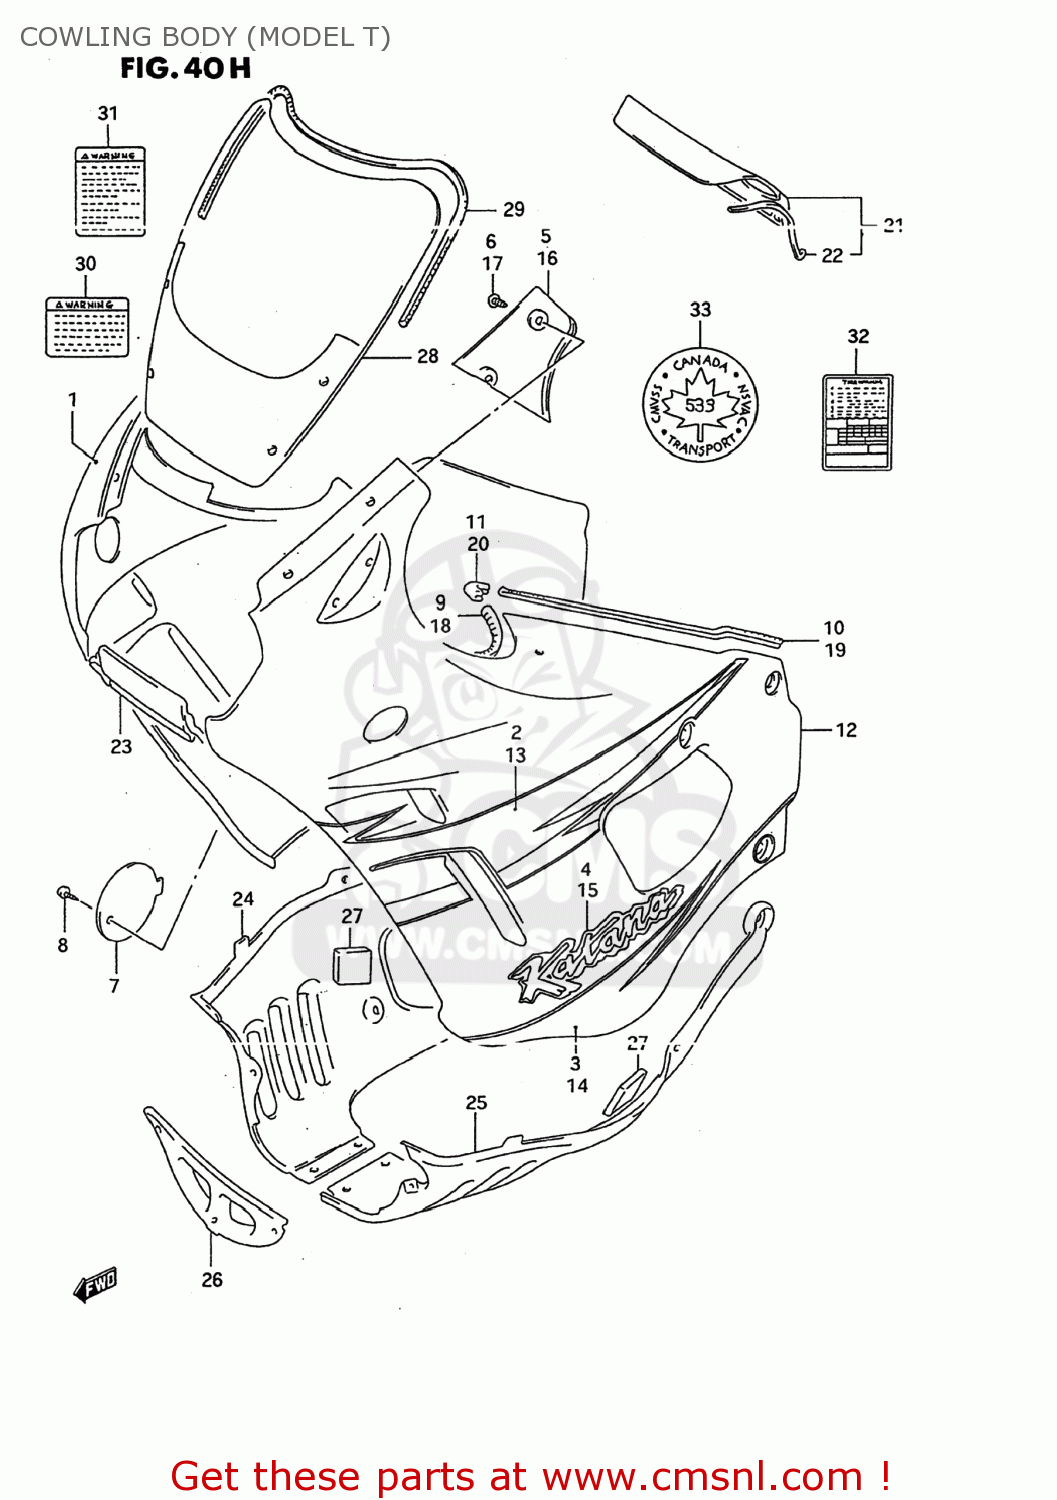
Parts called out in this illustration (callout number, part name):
1	COVER ASSEMBLY,COWLING,RIGHT
2	TAPE,BODY COWL SIDE UPR,R
3	TAPE,BODY COWL SIDE LWR,R
4	EMBLEM,COWLING SIDE
5	COVER,METER SIDE,RIGHT
6	SCREW
7	LID,OIL
8	SCREW(6X16)
9	MOLD,COWLING
10	MOLDING
11	JOINT,MOLDING END
12	COVER ASSEMBLY,COWLING,LEFT
13	TAPE,BODY COWLING SIDE,UPPER
14	TAPE,BODY COWL SIDE LWR,L
15	EMBLEM,COWLING SIDE
16	COVER,METER SIDE,L(GREEN)
17	SCREW
18	MOLD,COWLING
19	MOLDING
20	JOINT,MOLDING END
21	COVER,METER
22	MOLDING
23	PANEL,COWLING CTR
24	COVER,COWLING,UNDER,RIGHT
25	COVER,COWLING,UNDER,LEFT
26	COVER,COWLING UNDER FR
27	CUSHION,UNDER COWLING
28	WINDOW,COWLING
29	MOLDING,WINDSCREEN
30	LABEL,GENERAL WARNING
31	LABEL (WARNING SCREEN)
32	LABEL (TIRE AIR PRESSURE)
33	PLATE
